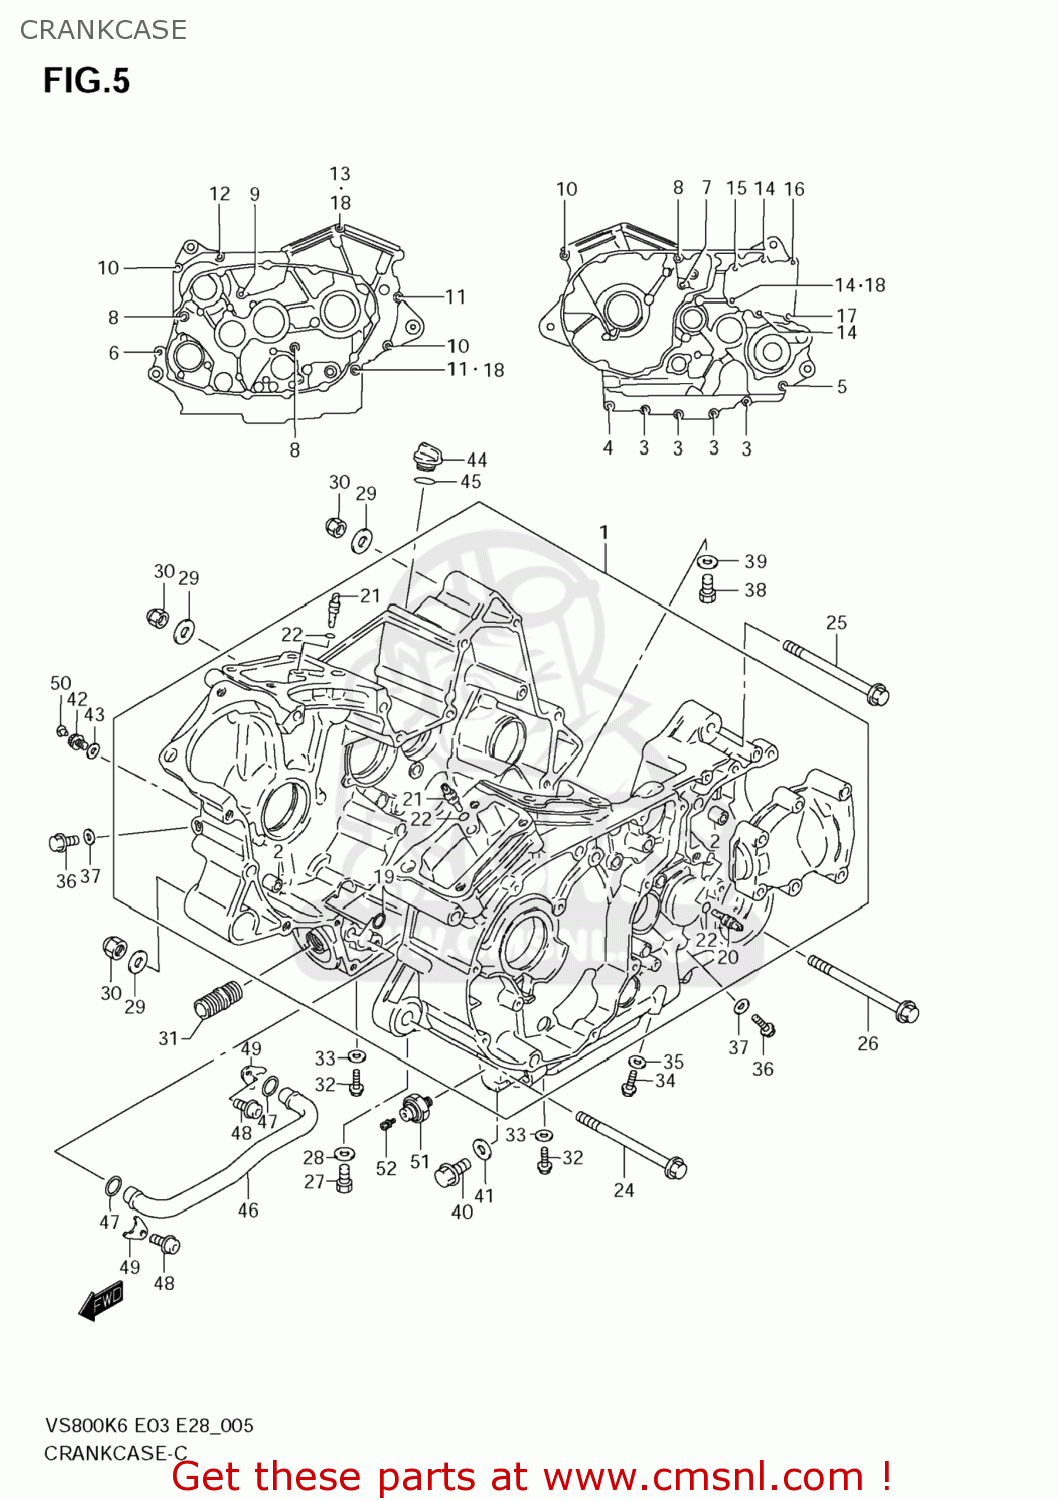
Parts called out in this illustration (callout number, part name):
1	CRANKCASE SET
2	PIN(8.4X11X20)
3	BOLT
4	BOLT
5	BOLT
6	BOLT
7	BOLT
8	BOLT
9	BOLT(8X120)
10	BOLT(8X95)
11	BOLT(8X105)
12	BOLT(8X120)
13	BOLT(8X160)
14	BOLT
15	BOLT
16	BOLT(8X55)
17	BOLT(8X65)
18	GASKET(8.2X14X1) (NAS)
19	O RING(D:1.9,ID:12.6)
20	JET,OIL GALLERY
21	JET,AIR(14)
22	O RING(D:1.2,ID:4)
23	WASHER(48.1X64X1.94)
24	BOLT(10X125)
25	BOLT(10X130)
26	BOLT(10X150)
27	PLUG(12X20)
28	GASKET(12.1X16.2X3.7) (NAS)
29	WASHER
30	NUT
31	UNION,OIL STAND
32	BOLT
33	GASKET(8.2X14X1) (NAS)
34	PLUG(10X12)
35	GASKET(10X14X3.6) (NAS)
36	BOLT
37	GASKET(5.8X13X1.2) (NAS)
38	PLUG
39	GASKET(16X22X2) (NAS)
40	PLUG(14X12)
41	GASKET(13.8X18.8X4.8) (NAS)
42	BOLT
43	GASKET(8.2X14X1) (NAS)
44	PLUG,ENGINE OIL FILLER
45	O RING(D:3.1,ID:16.8)
46	PIPE,OIL GALLERY
47	O RING(D:3.1,ID:14.8)
48	BOLT(6X12)
49	CLAMP,OIL PIPE
50	CAP(OD:11)
51	SWITCH ASSY,OIL PRESSURE
52	BOLT,OIL PRESSURE SWITCH
